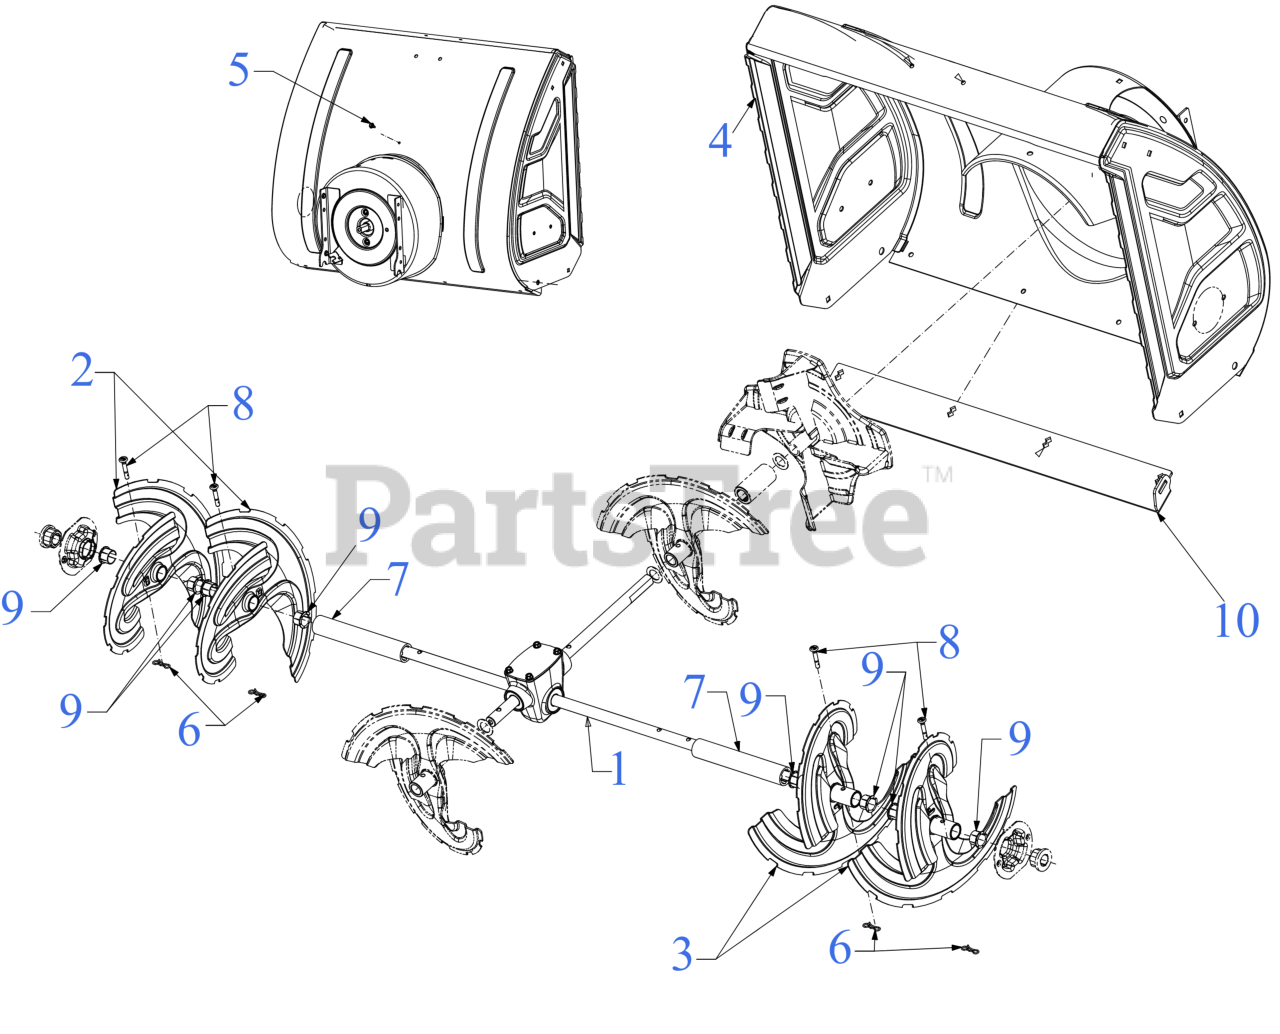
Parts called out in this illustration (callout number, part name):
1	GEARBOX ASSEMBLY 30"
4	30" HD LED AUGER HOUSING ASSEMBLY
5	SCREW M6-1 x .625
6	BOW TIE COTTER PIN 1/4-5/16
8	SHEAR PIN (.25 x 1.50)
8	Cub Cadet SHEAR PINS (3X SNOW)
8	Troy-Bilt SHEAR PINS (3X SNOW)
9	FLANGE BUSHING
